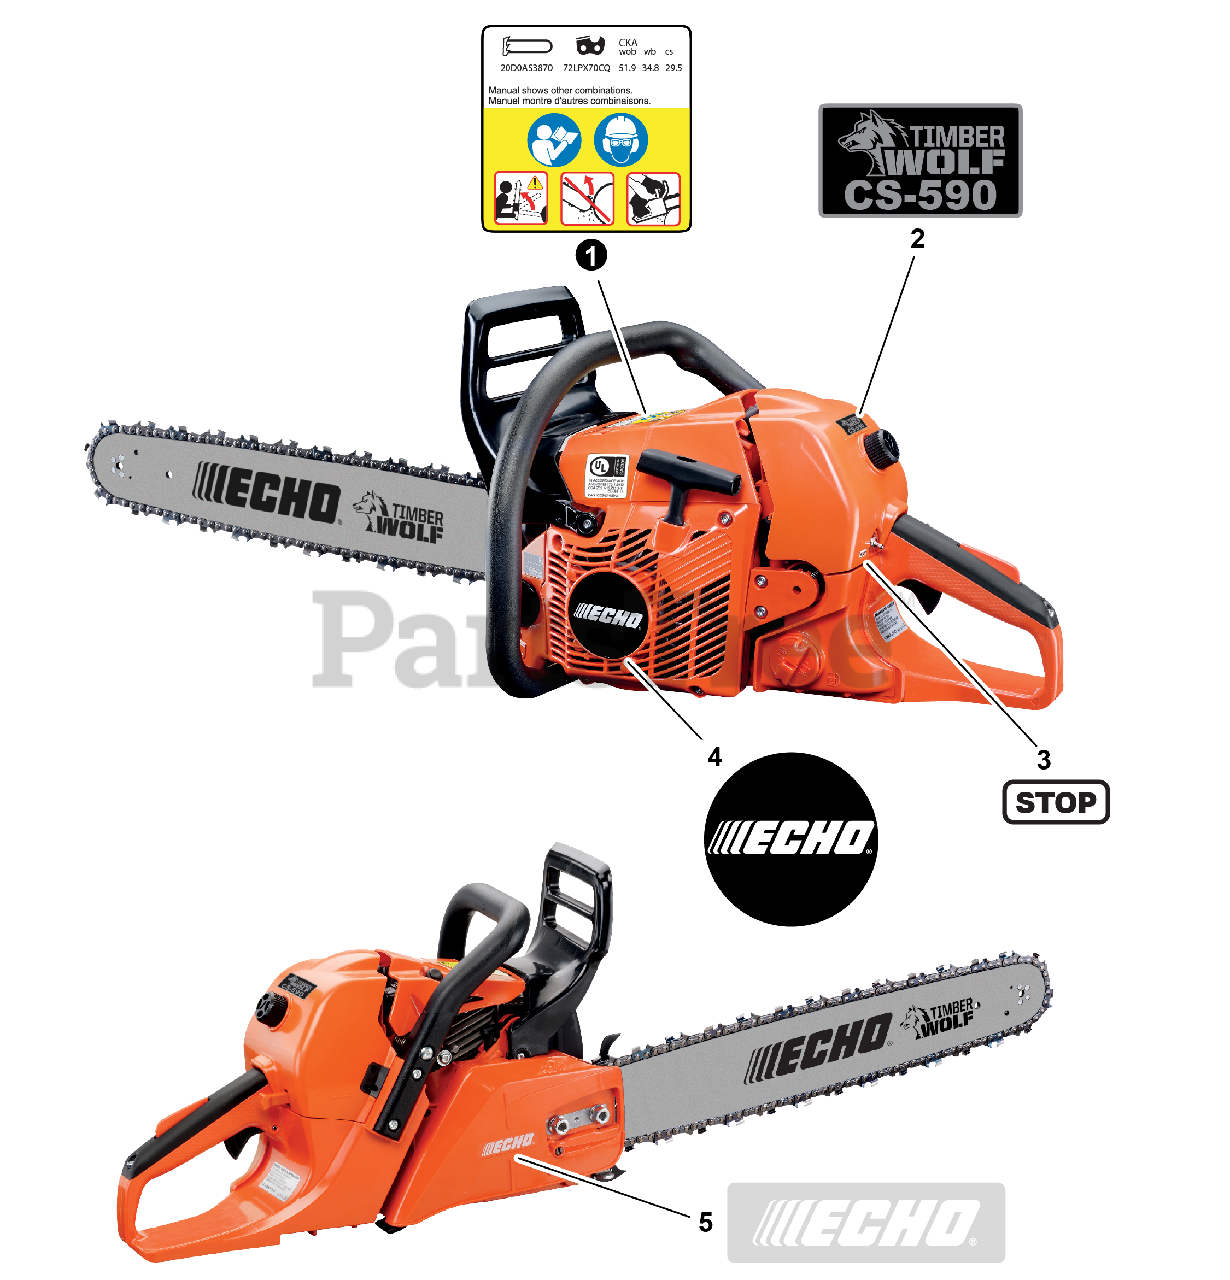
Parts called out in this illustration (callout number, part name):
1	LABEL - CAUTION
2	LABEL - MODEL CS-590 TIMBERWOLF
3	LABEL - STOP
4	LABEL - RECOIL STARTER
5	LABEL - ECHO
